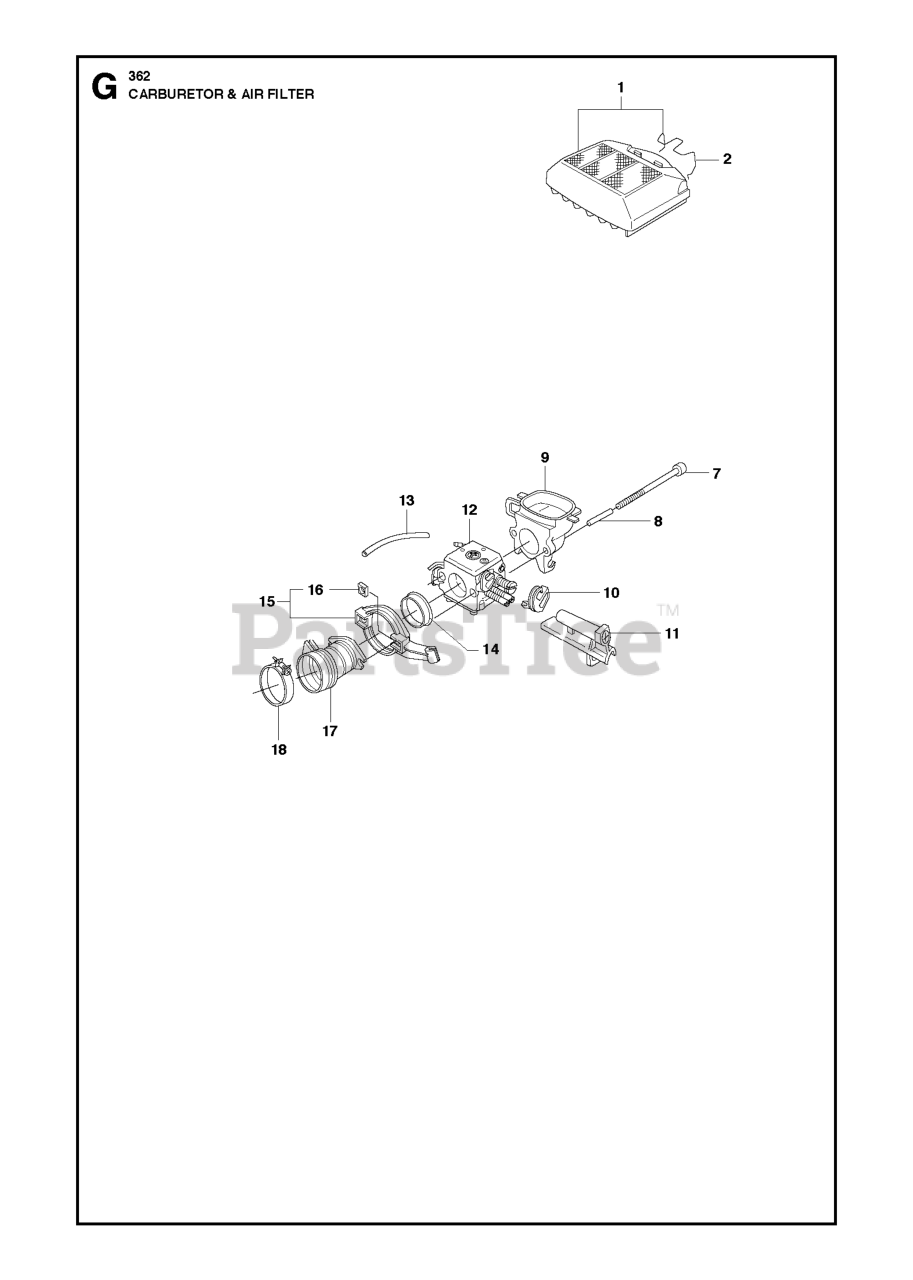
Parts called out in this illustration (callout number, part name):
1	AIR FILTER ASSY
2	AIR FILTER CLIP
9	HOLDER
12	CARBURETOR WALBRO HD-6B
17	INTAKE PIPE - EPA
18	CLAMP
